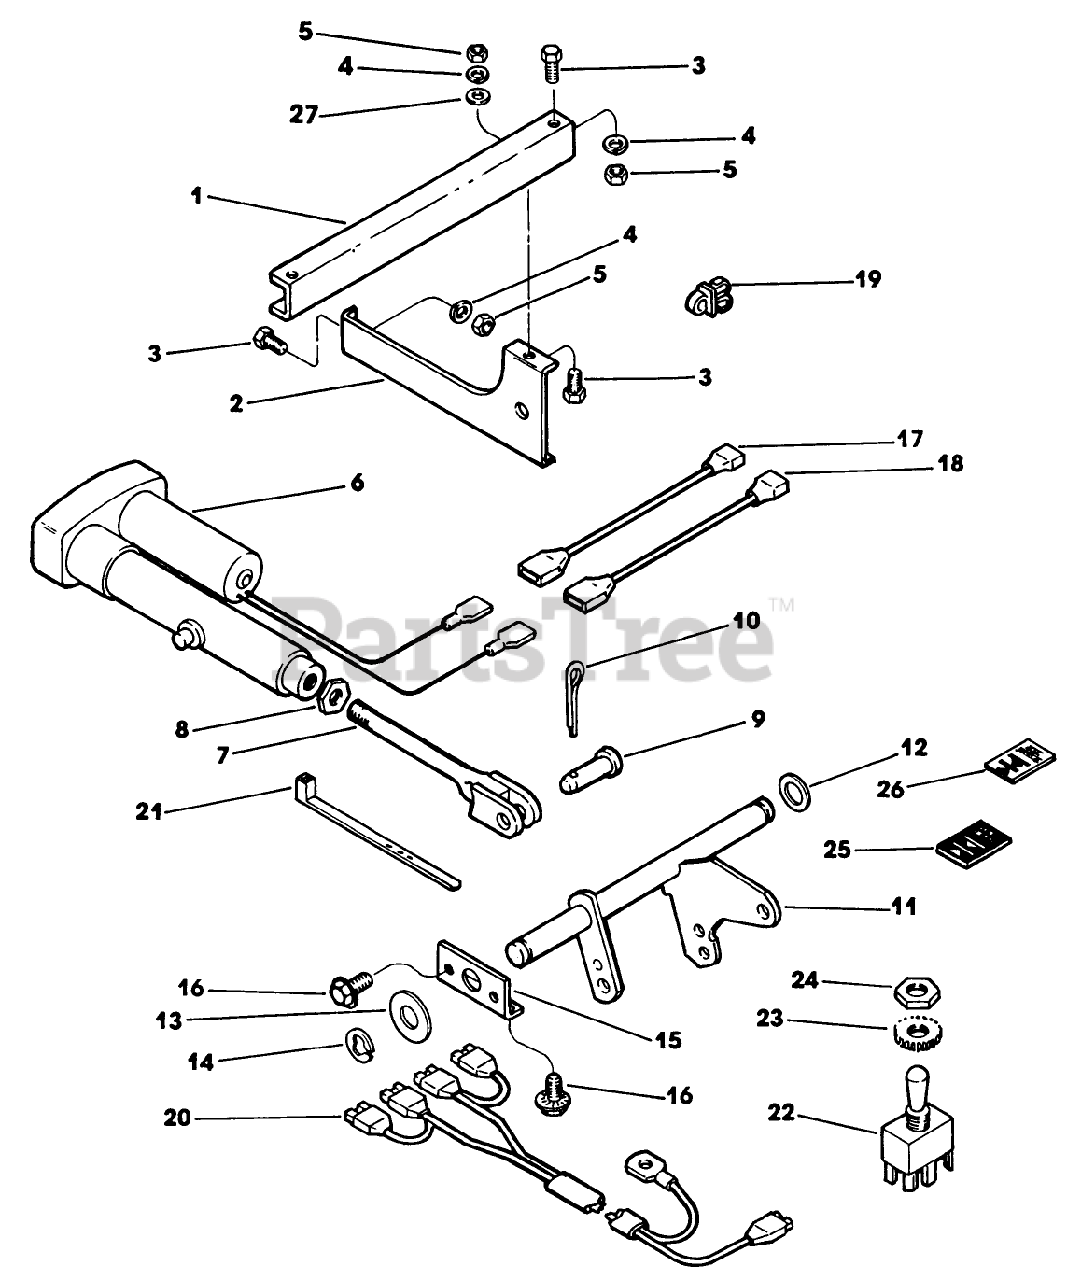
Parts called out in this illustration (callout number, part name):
3	SCREW - HEX
5	Nut, Hex
11	LIFT LEVER ASM
12	WASHER
13	WASHER
16	SCREW-HWH
18	WIRE ASSEMBLY
23	NIT KNURLED
27	Washer, Flat
